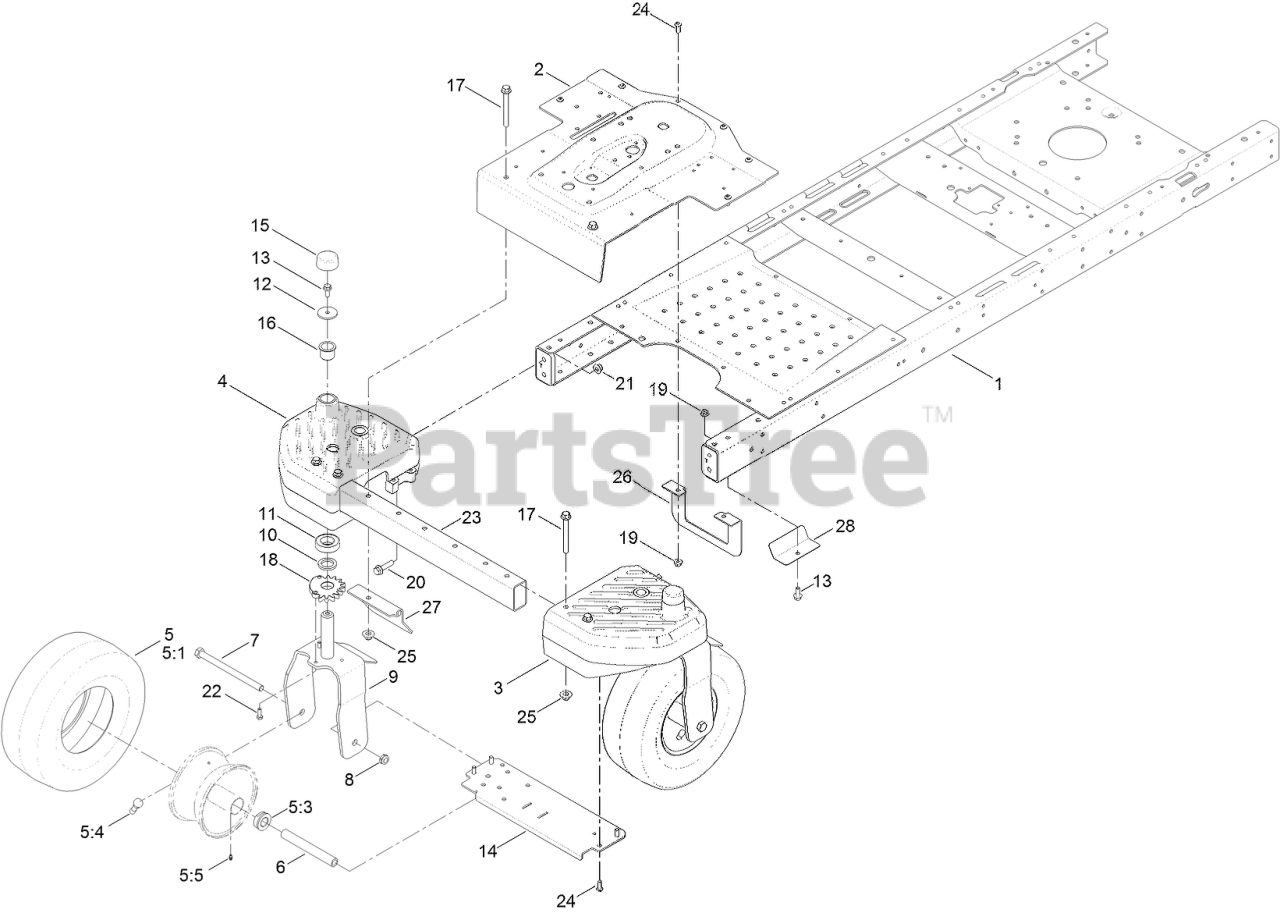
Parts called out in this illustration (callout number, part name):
1	FRAME ASM
2	PAN-STEER, FRONT
3	HOUSING-SPINDLE, LH
4	HOUSING-SPINDLE, RH
5	Caster Wheel ASM
5:3	BUSHING-FLANGE
5:4	STEM-VALVE
5:5	FITTING-GREASE
6	BUSHING-SPANNER
7	SCREW-HH
8	NUT-LOCK, NI
9	CASTER FORK ASM
10	WASHER-THRUST
11	BEARING-BALL
12	WASHER-FLAT
13	SCREW-HHF
14	PLATE-BRIDGE, NARROW
15	CAP-CASTER
16	BUSHING-PIVOT
17	SCREW-HHF
18	GEAR-WHEEL, 15 TEETH
19	NUT-HF, NI
20	SCREW-HHF
21	NUT-HF, NI
22	SCREW-HH
23	TUBE-FRONT, NARROW
24	SCREW-HSBH
25	NUT-FLANGE, NI
26	BRACKET-UPSTOP
27	GUARD-FRONT
28	PLATE-GUARD
